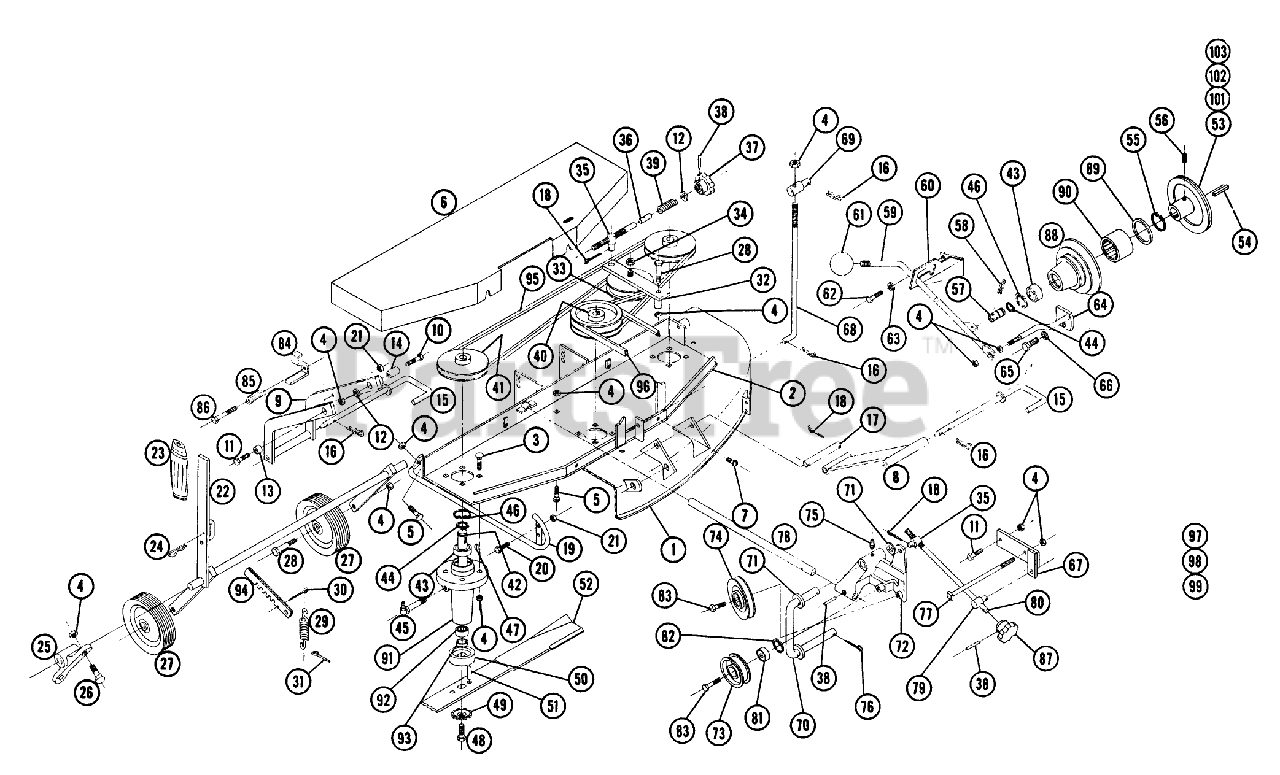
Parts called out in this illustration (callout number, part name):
1	Ass-y. Deck
2	Ass-y. Channel-Deck Support
3	Bolt 3/8-16 x 1
5	Bolt-3/8-16 x 3/4
6	Cover-Deck
10	Bolt, 3/8 16 x 2
11	Bolt 3/8-16 x 1
12	Washer
15	Ass-y. Pin Lift Link
16	Hairpin
18	Cotter Pin
19	Washer
20	Bolt Hex 5/16-18
21	Nut-Nylok
22	Ass-y. Gage Wheel Adj. Rod
24	Hairpin
25	Bearing-Cast Iron
26	Bolt 3/8-16 x 1
28	Bolt-Shoulder
30	Cotter Pin 1/8 x 1/2
31	Cotter Pin
32	Ass-y.-Idler Plate
34	Locknut-1/2-13
35	Trunnion
36	Rod-Mower Adj.
37	Knob-Adj.
38	PIN-ROLL
39	Spring
44	Snap Ring 3/4 I.D.
46	Snap-Ring 1 5/8 Bore
47	KEY-WOODRUFF
48	Screw - Nylock 3/8-16 x 7/8
51	SPIROL ROLL PIN
54	KEY-SQUARE
55	Snap Ring-1 1/8 Int. Truarc
56	Set Screw #10-24 x 1/4 Soc. Hd.
57	Shaft
58	Hairpin
59	ROD ASSY
62	Bolt Hex 5/16-18
63	Lockwasher
64	Ass-y.-Plate
65	Bolt, 7/16 14 x 1
66	Lockwasher 3/8
67	Ass-y.-Belt Adj. Bracket
69	LIFT STUD
71	Washer
72	Bracket-Idler Mtg.
76	Cotter Pin 5/32 x 1 1/4
77	Bolt-Hex. 3/8-16 x 8 1/2
78	Rod-Leveling
79	Stud
81	BEARING
82	Snap Ring 1 3/8 Bore
83	Bolt 3/8-16 x 1 1/4 Nylok
85	SPRING-COMPRESSION
86	Bolt-Hex 3/8-16 x 2
88	Housing-Clutch
94	Ass-y. Arm-Gage Wheel
95	V-BELT
98	Decal Belt Installation
99	Wrech #10 Allen
102	CLUTCH FACING
103	Rivet-Clutch Facing
